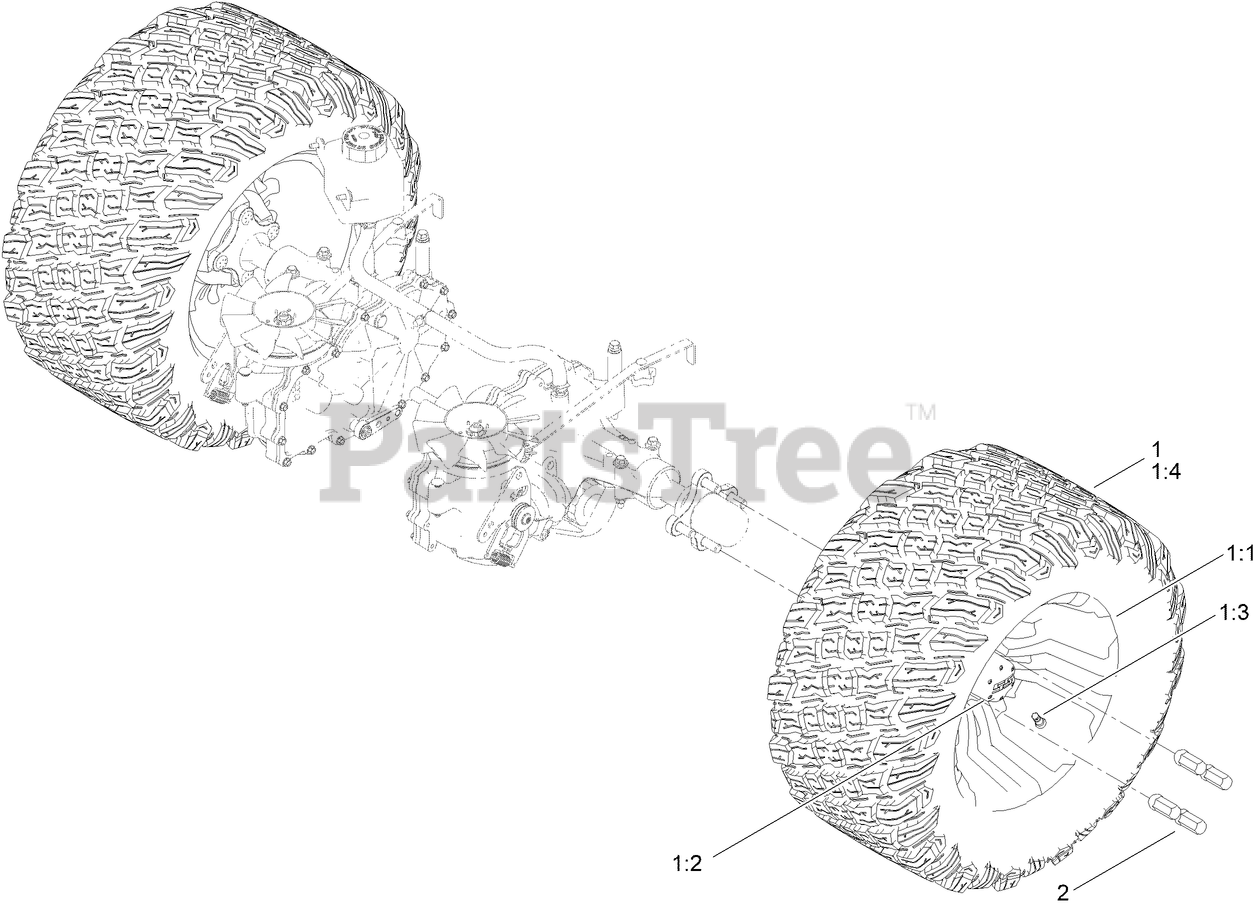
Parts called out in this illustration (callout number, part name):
1	TIRE ASM
1:2	CAP-WHEEL
1:3	STEM-VALVE
2	NUT-LUG
